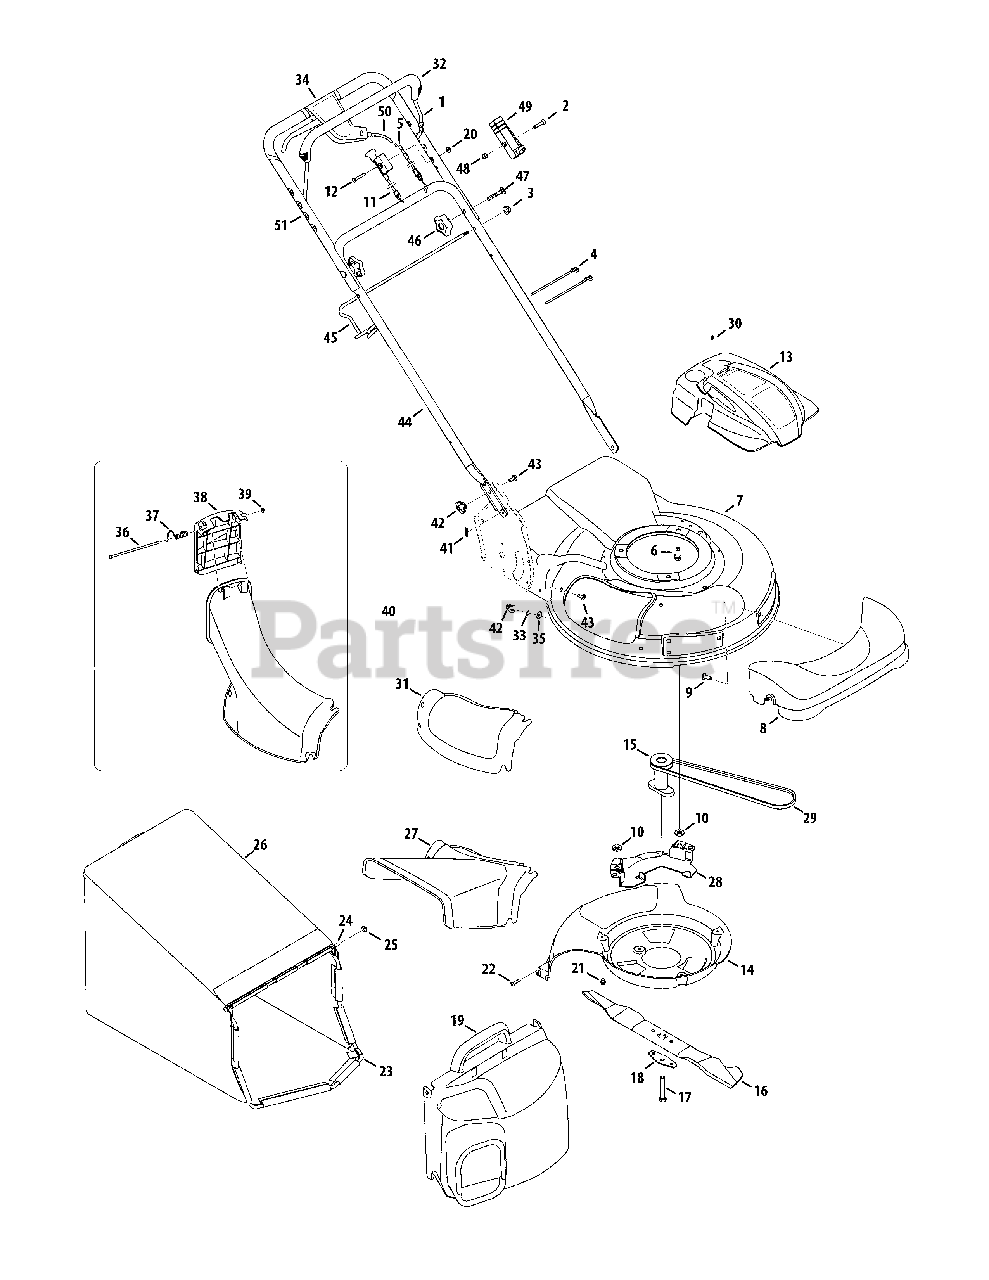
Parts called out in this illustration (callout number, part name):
2	Machine Screw, 1/4-20 x 1.310
3	Flange Lock Nut, 5/16-18
4	Cable Tie
5	Control Cable
6	TT Screw, 3/8-16 x 1.00
9	HL Screw, 5/16-14 x .750
10	Washer, Flat, .407 x .812 x .135
11	Choke Cable
12	Screw, 1/4-20 x 1.50
13	Engine Shroud
14	Rear Baffle
15	Blade Adapter
16	21-inch Mulching Blade
17	HH Cap Screw, 3/8-24 x 2.50
18	Bell Blade Spacer
19	Grass Bag Cover Assembly
20	Flange Lock Nut 1/4-20
21	TT Screw 1/4-20 x .375
22	HL Screw 1/4-15 x .75
24	Grass Bag Pivot Rod
25	Cap Speed Nut
26	Grass Bag Assembly
27	Side Discharge Chute
28	Belt Keeper
29	V-Belt
30	Screw, #12-16 x 1.00
31	Mulch Cover
32	Bail Cover
34	Drive Control Assembly
35	Washer, Flat, .260 x .720 x .060
36	Chute Door Pivot Rod
37	Torsion Spring
38	Top Discharge Door Chute
40	Top Discharge Chute Assembly
41	Cotter Pin
42	Wing Nut
43	Carriage Screw 1/4-20 x .75
46	Star Knob
47	Carriage Bolt 5/16-18 x 2
48	Hex Lock Nut 1/4-20
49	ERS Housing
50	Drive Cable
